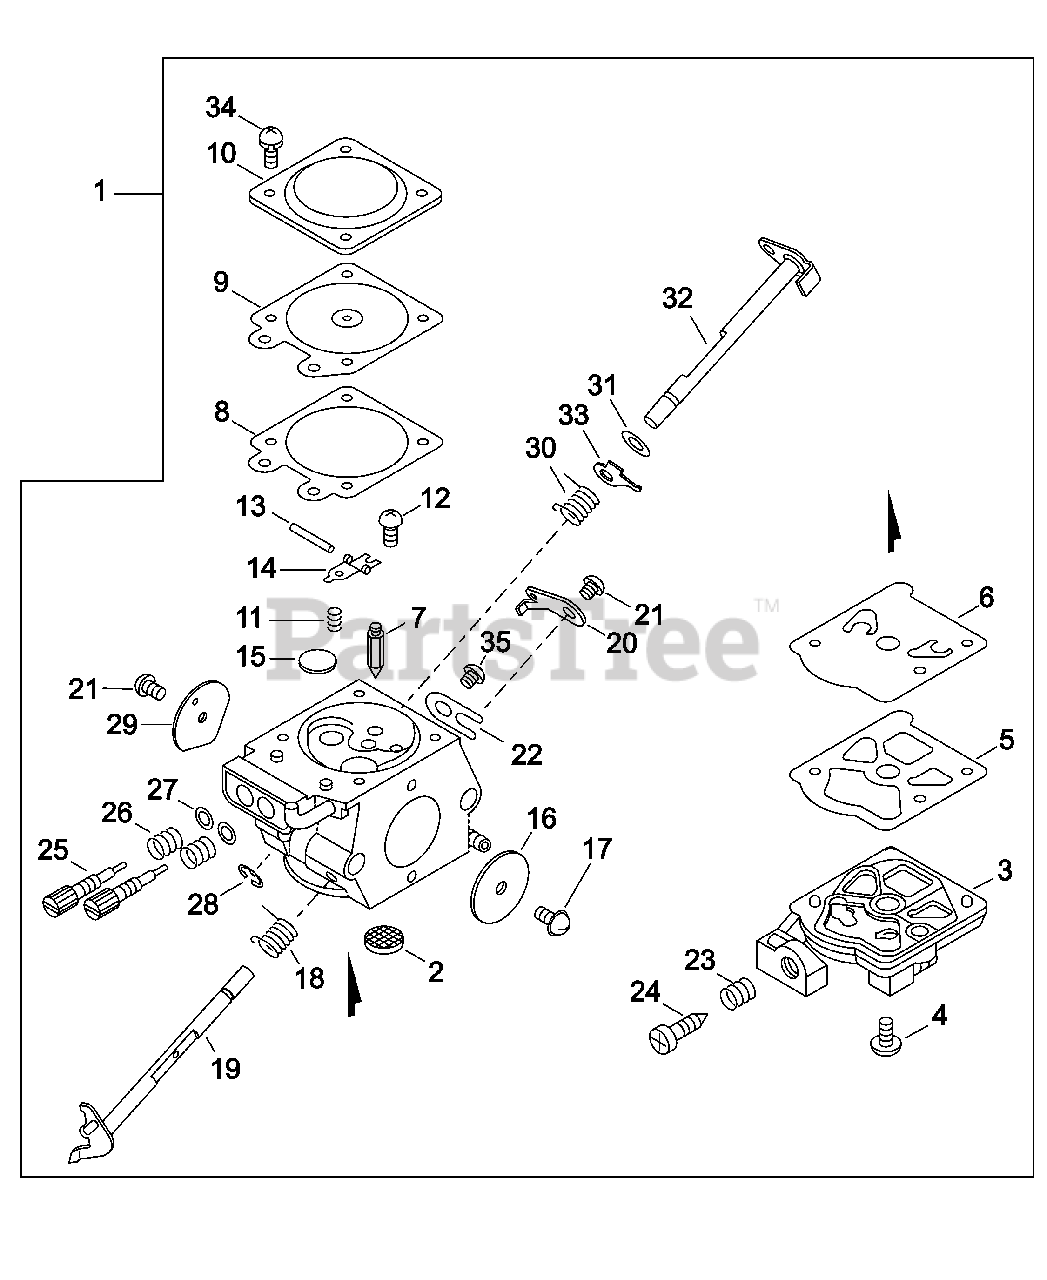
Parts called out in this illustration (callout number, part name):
1	CARBURETOR WT-1110
2	SCREEN, INLET
3	COVER, PUMP
5	GASKET, PUMP
6	DIAPHRAGM, PUMP
7	VALVE, INLET NEEDLE
8	GASKET, METERING DIAPHRAGM
9	DIAPHRAGM, METERING
10	COVER, METERING DIAPHRAGM
11	SPRING, METERING LEVER
13	PIN, METERING LEVER
14	LEVER, METERING
15	PLUG, WELCH
16	VALVE, THROTTLE
18	SPRING, THROTTLE RETURN
19	SHAFT ASSY, THROTTLE
20	LEVER, THROTTLE
22	CLIP, THROTTLE SHAFT
23	SPRING, IDLE ADJUST
24	SCREW, IDLE ADJUST
25	NEEDLE, MIXTURE
26	SPRING, NEEDLE
27	WASHER
29	VALVE, CHOKE
32	SHAFT, CHOKE
33	LEVER, FAST IDLE
